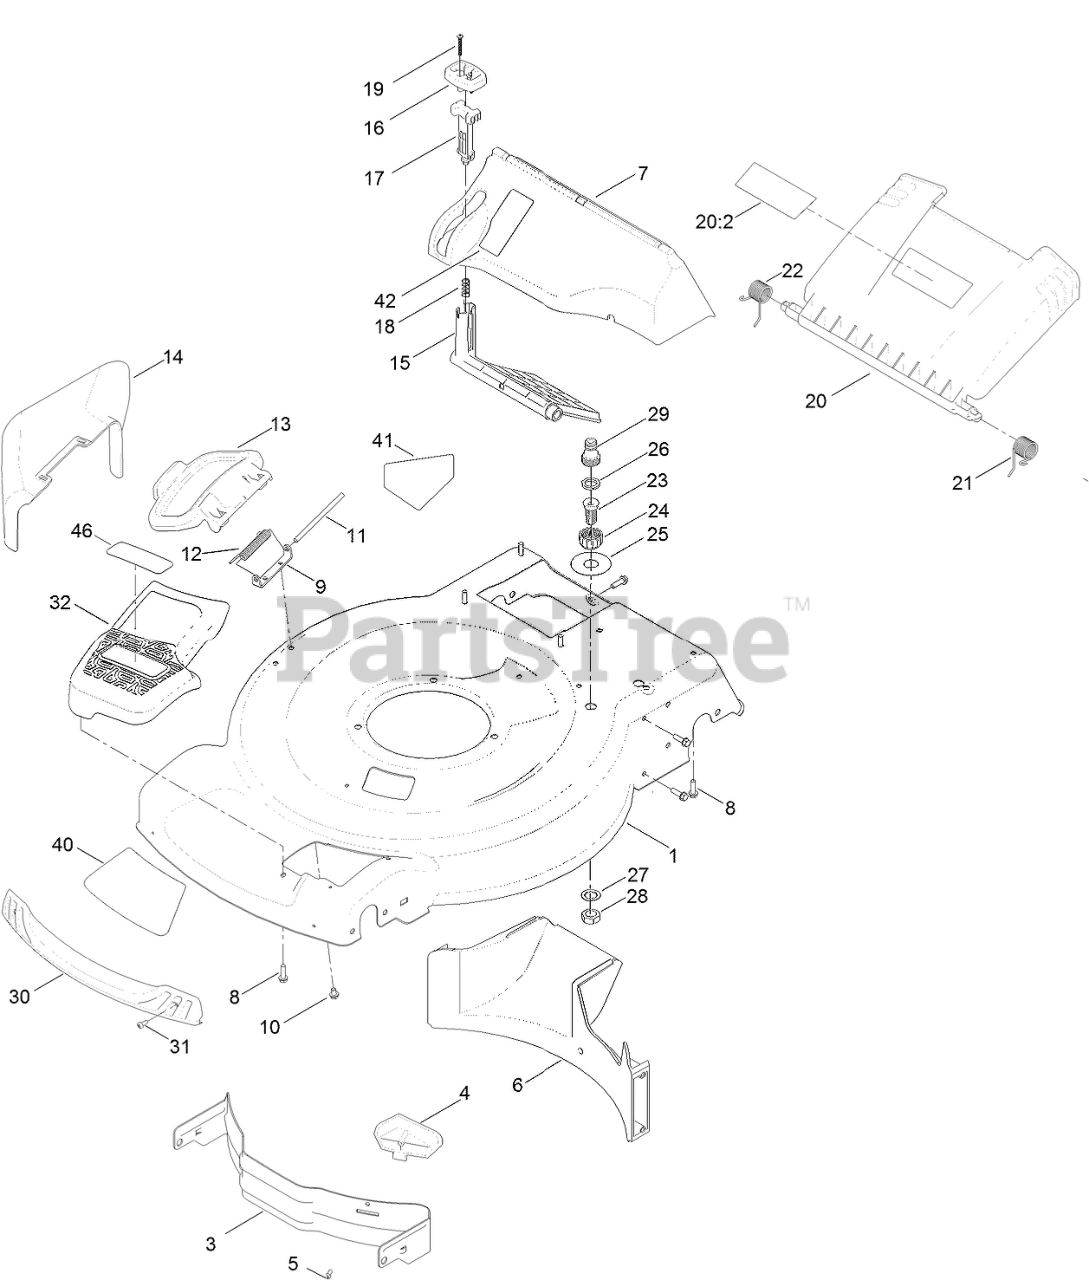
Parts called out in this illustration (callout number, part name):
1	HOUSING ASM
3	BAFFLE-FRONT
4	KICKER-FRONT
5	SCREW-PPH
6	BAFFLE-REAR
7	CHUTE-RECYCLE
8	SCREW-HWH
9	BRACKET-COVER
10	SCREW-HWH
11	ROD-COVER
12	SPRING-TORSION
13	DEFLECTOR-SIDE
14	CHUTE-DISCHARGE, SIDE
15	DEFLECTOR-RECYCLE
16	KNOB-RECYCLE
17	LATCH-RECYCLE
18	SPRING-COMPRESSION
19	SCREW-PPH
20	REAR DOOR ASM
20:2	DECAL-WARNING
21	SPRING-TORSION
22	SPRING-TORSION
23	PORT-WASHOUT
24	COUPLING-HOSE, WASHOUT PORT
25	DECAL-PORT, WASHOUT
26	WASHER-SEAL, WASHOUT PORT
27	WASHER-TOOTH, INTERNAL
28	NUT-JAM
29	ADAPTER-CONNECT, QUICK
30	BUMPER
31	SCREW-FORMING, THREAD
32	COVER-BELT, FRONT
40	DECAL-DECK
41	DECAL-DANGER
46	DECAL-COVER
